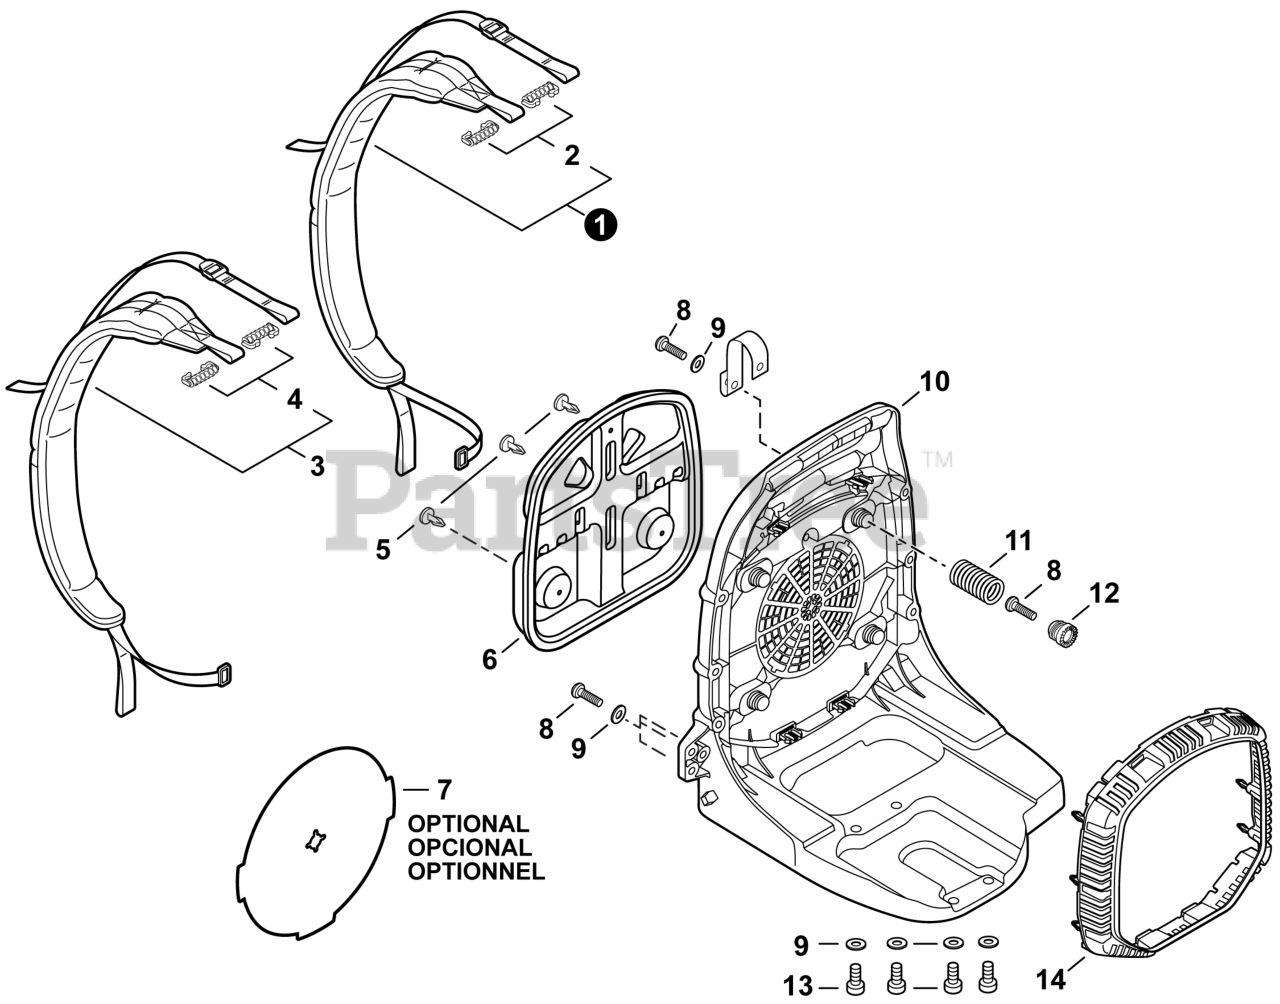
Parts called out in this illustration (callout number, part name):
1	HARNESS ASSY, RIGHT
3	HARNESS ASSY, LEFT
6	CUSHION, BACKPACK
7	INSERT, COLD WEATHER
8	BOLT, TORX 5x20
9	WASHER 5.5x16x2T
10	FRAME, BACKPACK
11	SPRING, COMPRESSION
12	HOLDER, SPRING
13	BOLT, TORX 5x20
14	GUARD, DEBRIS
